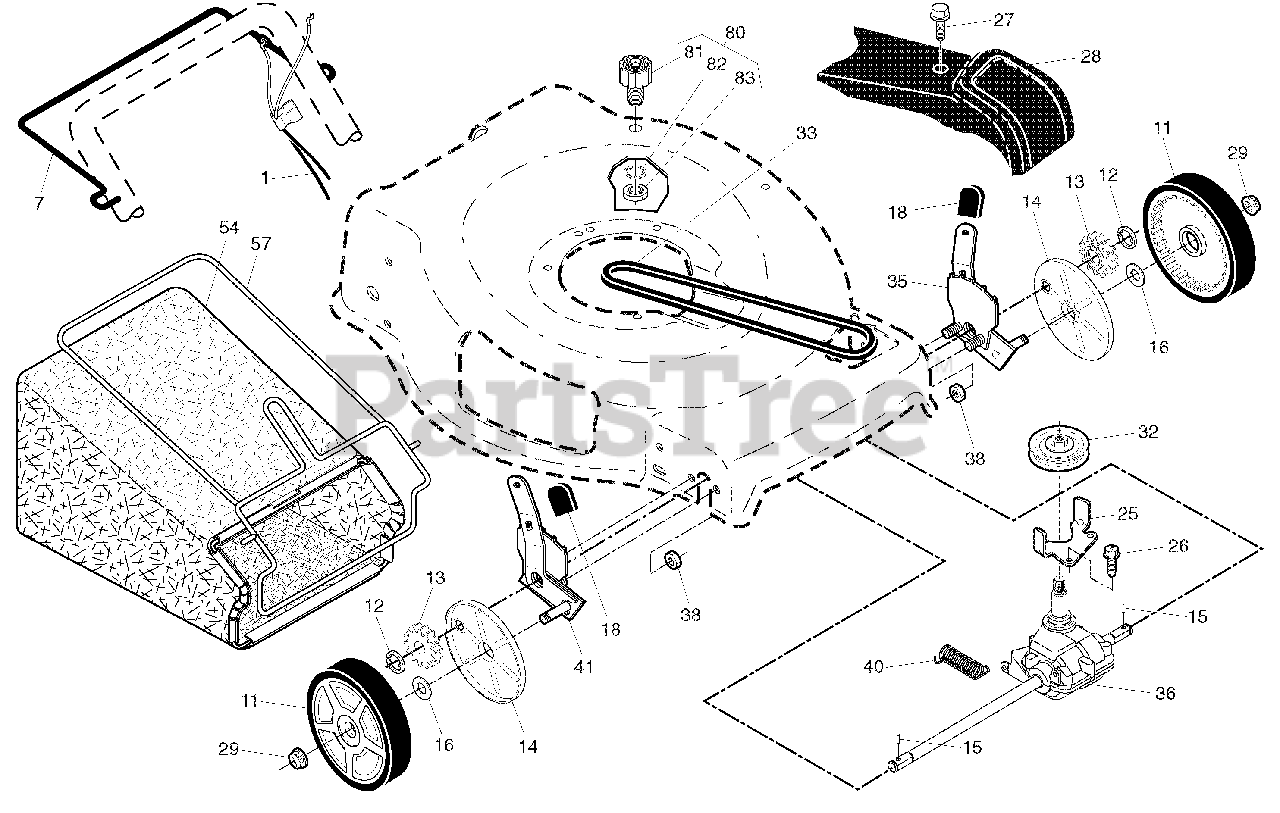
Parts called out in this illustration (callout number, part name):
1	DRIVE CONTROL ASSY (W/CABLE)
7	Control Bar, Drive
11	WHEEL & TIRE ASSEMBLY
14	DUST COVER
15	Pawl, Drive
16	Washer, Flat 3/8
18	Selector Knob
25	BELT KEEPER
26	SCREW, HI-LO THREAD #12 X 5/8
27	Pan Head Tapping Screw #10-24
28	DRIVE COVER
29	Nut, Hex
32	DRIVE PULLEY
35	KIT WHEEL ADJUSTOR FRONT LH
36	GEARCASE ASSEMBLY, COMPLETE
38	LOCKNUT, HEX 1/4-20
41	WHEEL ADJUSTER, FRONT RH W/BRG
54	GRASSBAG
57	FRAME, GRASSBAG
80	KIT, WATER WASHOUT ASSEMBLY
81	FITTING, WATER WASHOUT
82	WASHER, LOCK, INTERNAL TOOTH
83	LOCKNUT, HEX, WITH O-RING
